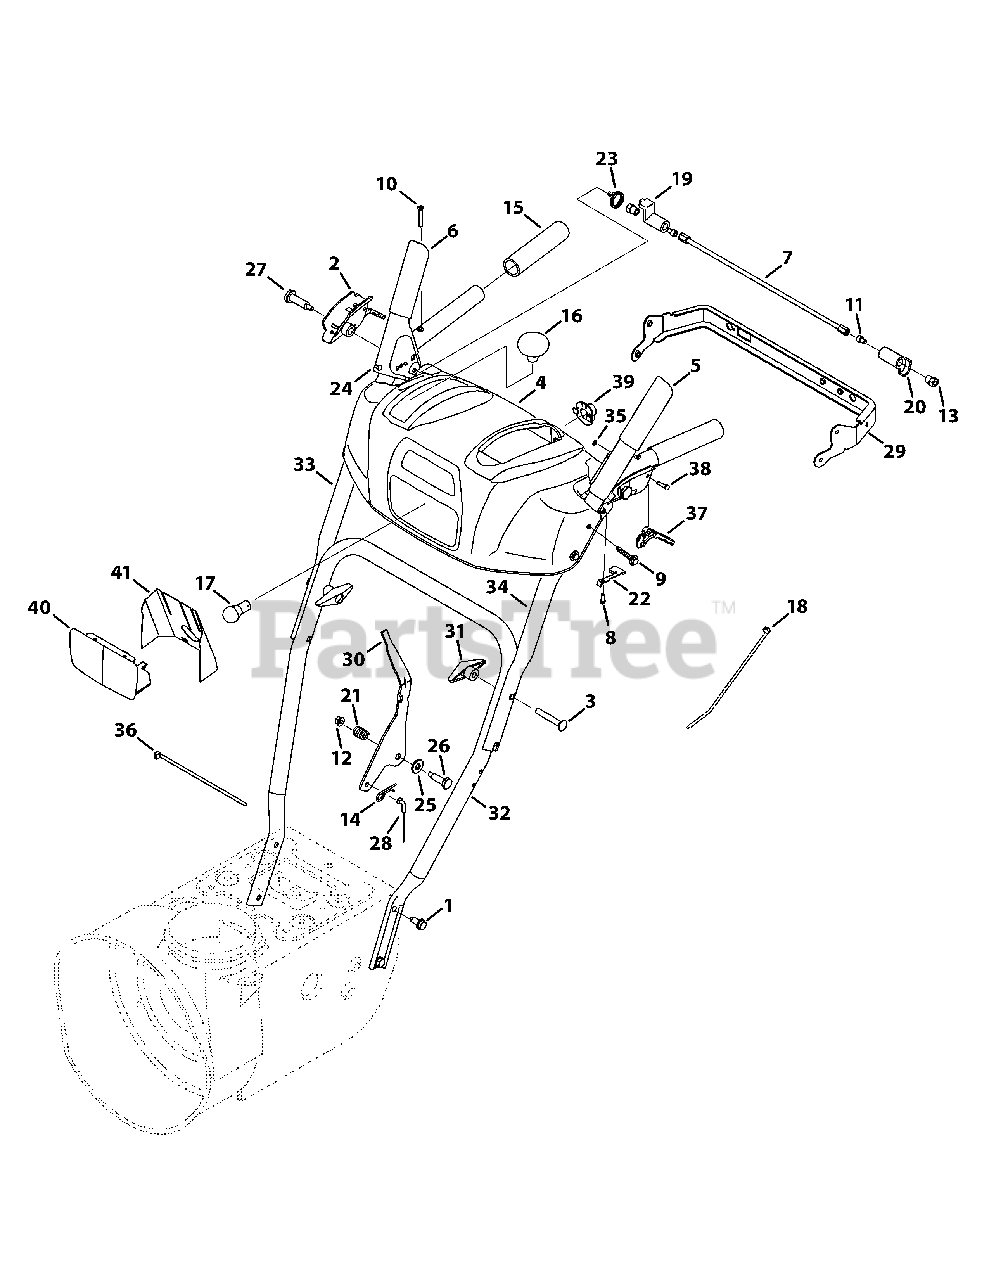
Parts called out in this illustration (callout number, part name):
1	Hex Screw, 5/16-18 x .750
2	Handle Clutch Lock LH Assy
2	Handle Clutch Lock RH Assy
3	Carriage Screw, 5/16-18 x 2.25
4	Handle Panel
5	Handle Engagement Assembly LH
6	Handle Engagement Assembly RH
8	Screw, 8-16 x 0.50
9	Screw, 1/4-20 x 1.625
10	Screw, 10-24 x 0.375
11	Socket Screw, 1/4-20 x .50
12	Flange Lock Nut, 1/4-20
13	Shoulder Nut, 1/4-20
14	Click Pin, .092 x 1.64
15	Handle Grip
16	Shift Knob
18	Cable Tie
20	Clutch Lock Cam
21	Compression Spring
22	Clutch Lock Spring
23	Torsion Spring
24	Rubber Bumper
25	Flat Washer
26	Shoulder Screw
27	Shoulder Screw, 1/4-20 x 1.345
28	Speed Cable Selector
29	Panel Bracket
30	Shift Lever
32	Lower Handle
33	Upper Handle RH
34	Upper Handle LH
36	Cable Tie
37	Clutch Trigger
39	Light Socket
41	Lens Label
